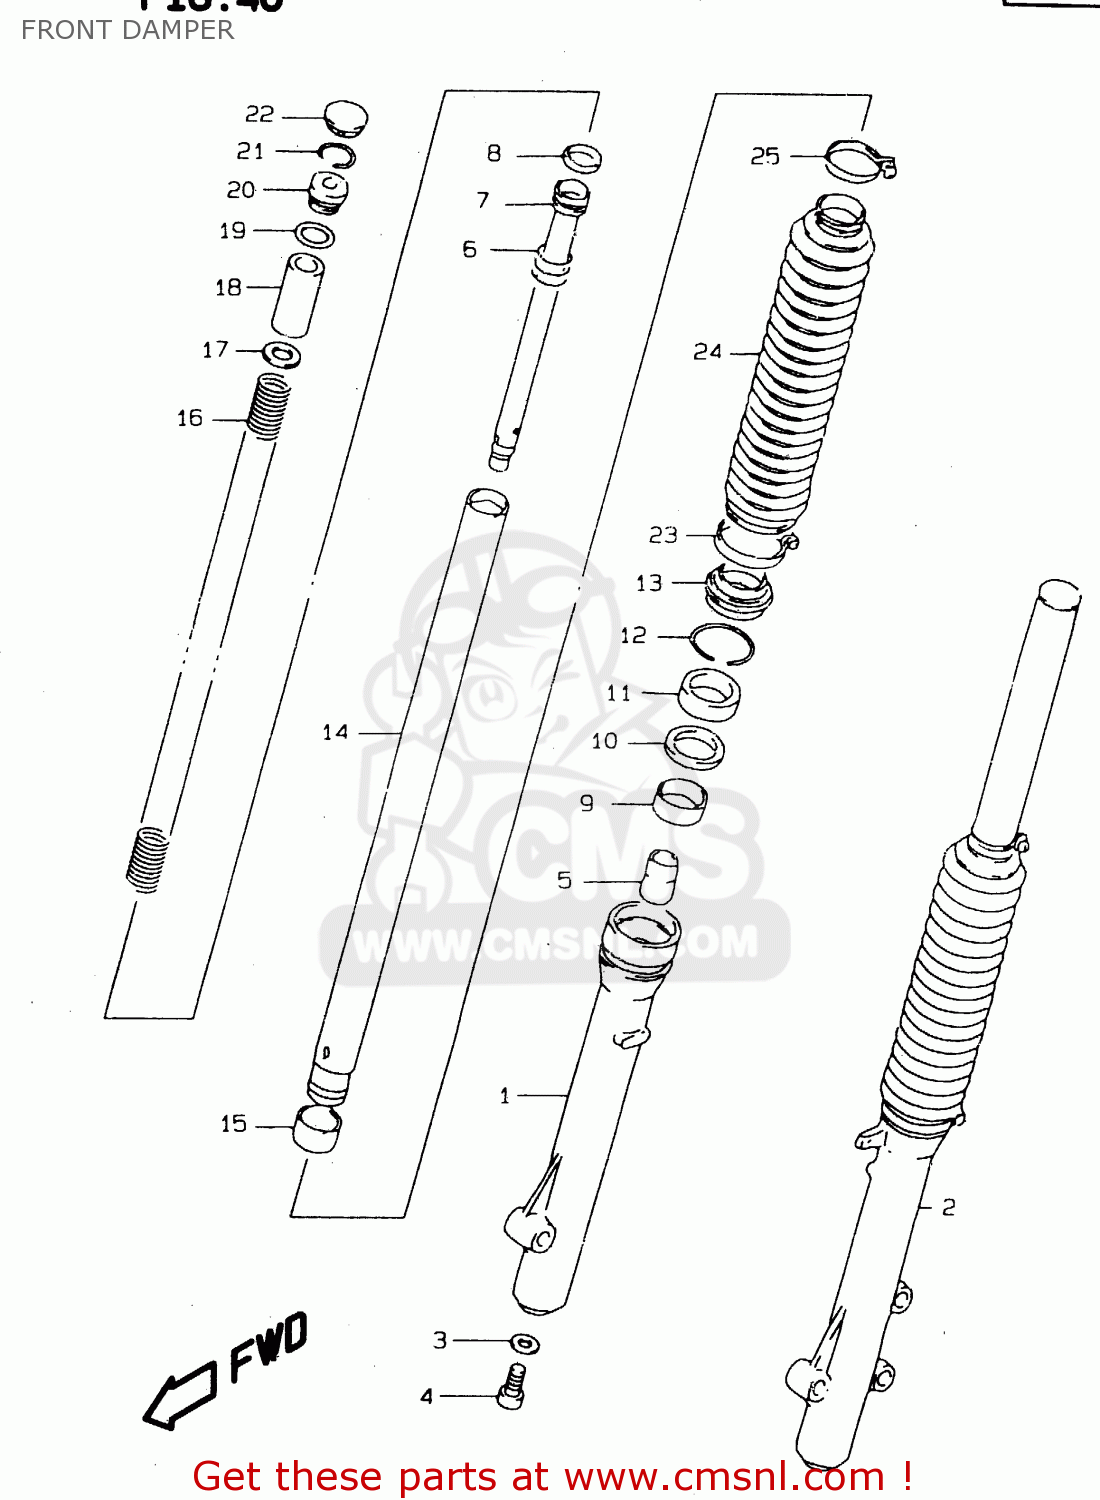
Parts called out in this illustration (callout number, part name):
1	TUBE,OUTER,R
2	TUBE,OUTER,L
3	GASKET (NAS)
4	BOLT,CENTER (8X18)
5	PIECE,OIL LOCK
6	SPRING,REBOUND
7	CYLINDER
8	RING,PISTON
9	BUSH,GUIDE
10	SPACER,SEAL
11	SEAL,OIL 35X48X11
12	RING,OIL SEAL STOPPER
13	SEAL,DUST
14	TUBE,INNER
15	PISTON
16	SPRING,MAIN
17	SPRING,JOINT
18	SPACER,SPRING
19	O RING
20	SPRING SEAT B
21	RING,STOPPER
22	CAP
23	BAND,BOOT LWR
24	BOOT
25	BAND
